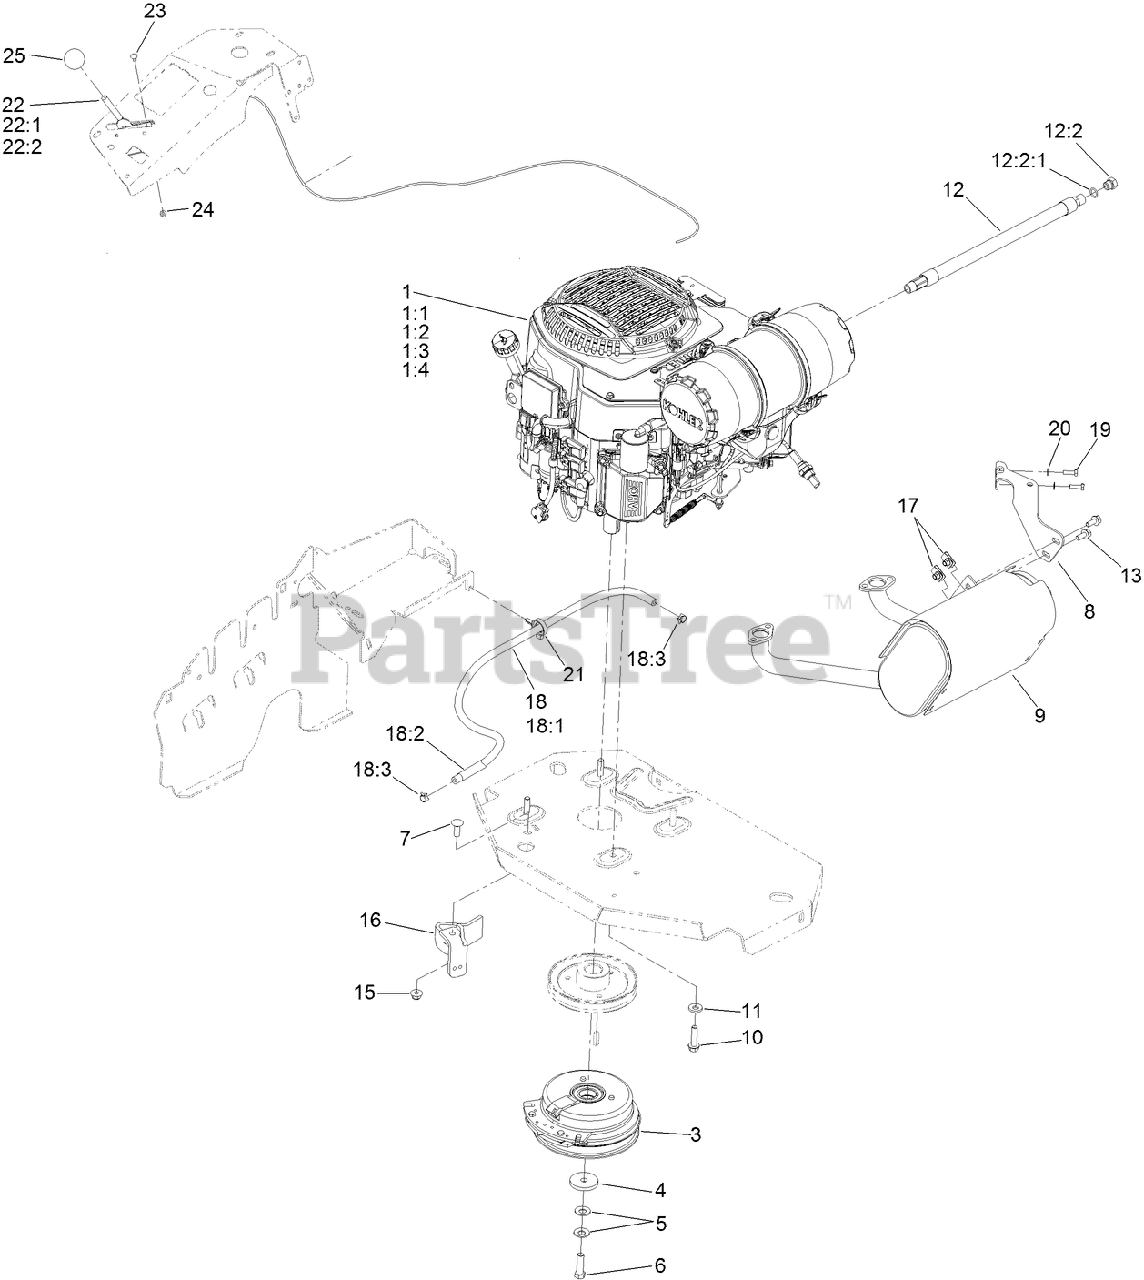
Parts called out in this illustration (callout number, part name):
1:1	KOHLER 52 050 02-S ENGINE OIL FILTER
1:2	KOHLER 25 083 01-S ENGINE AIR FILTER
1:3	KOHLER 25 083 04-S SAFETY FILTER
1:4	KOHLER 25 050 42-S FUEL FILTER
3	CLUTCH KIT
4	WASHER-CLUTCH
5	WASHER-SPRING
6	SCREW-HH, W/LOCTITE
7	SCREW-CARR
8	MUFFLER BRACKET KIT
9	MUFFLER KIT
10	SCREW-HWH
11	WASHER-BELLEVILLE
12	OIL DRAIN HOSE ASM
12:2	PLUG-HH
12:2:1	O-RING
13	SCREW-HH
15	NUT-HF, NI
16	CLUTCH-ANCHOR
17	NUT-U
18	FUEL LINE ASM
18:1	HOSE-FUEL
18:2	SLEEVE-THERMAL
18:3	CLAMP-HOSE
19	SCREW-HH
20	WASHER-SPRING
21	CLAMP-HOSE
22	THROTTLE CONTROL ASM
22:1	LEVER-THROTTLE
23	BOLT-CARR
24	NUT-LOCK, NI
25	KNOB-BALL
